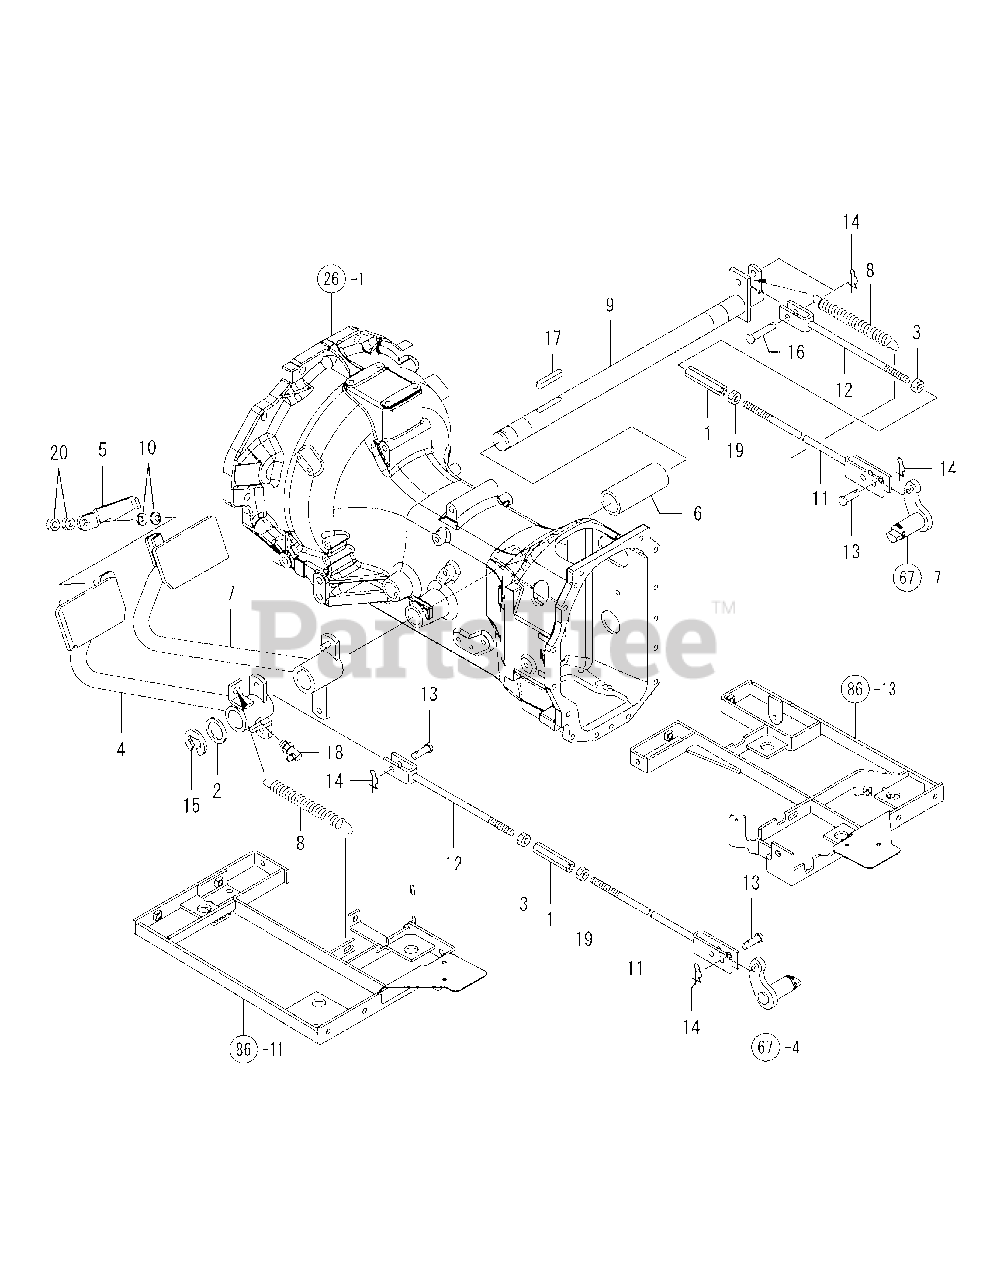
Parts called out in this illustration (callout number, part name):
2	Spacer 25.2X34X2
3	Nut W/Washer 8
4	Pedal L Cmp, Brake
5	Conector,Brake
7	Pedal Assy, Brake R
9	Shaft, Brake Pedal
10	Spring, Conical
14	Pin 8,Come-Off Snap
18	Nipple B, Grease
